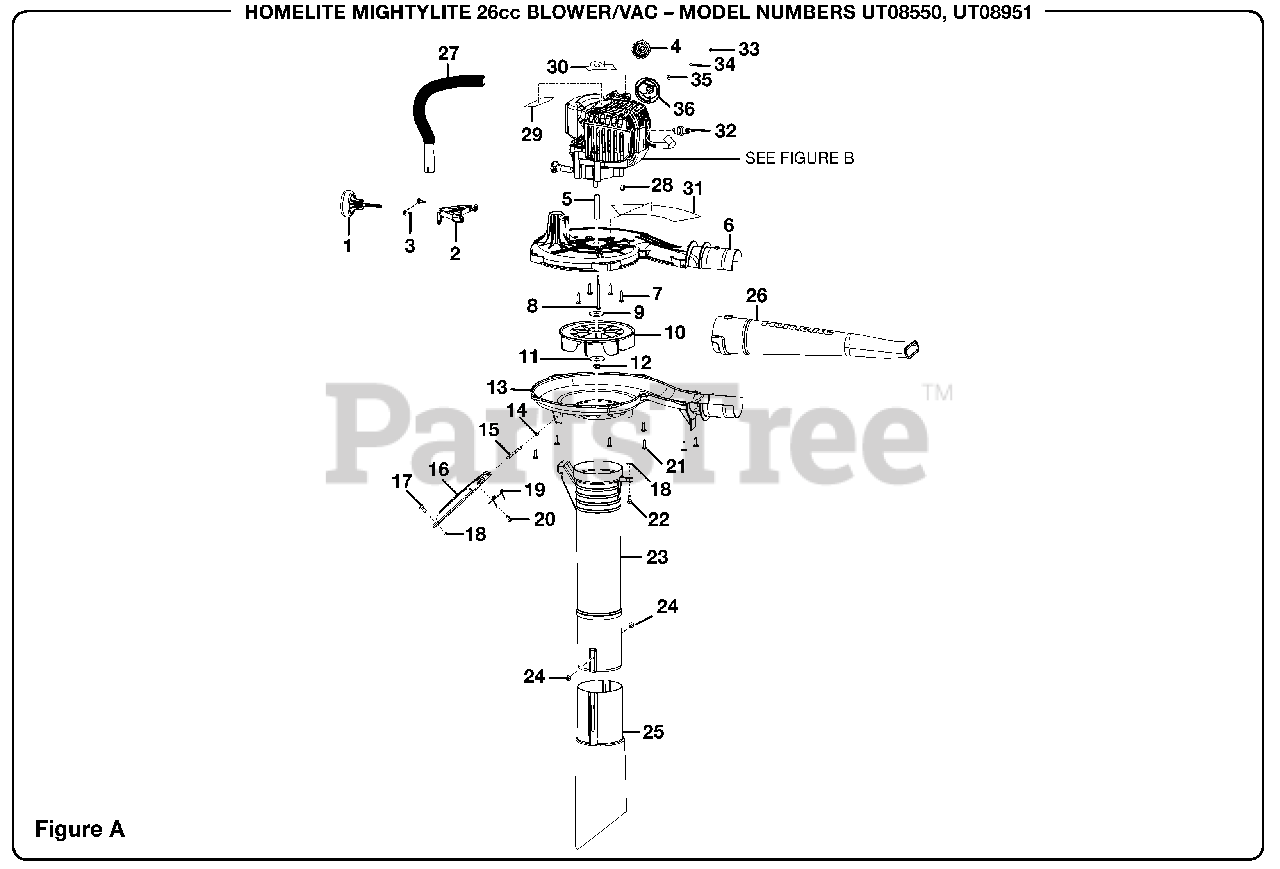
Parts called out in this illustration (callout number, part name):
1	Handle Knob
2	Handle Adaptor
3	Screw (M4, special)
4	Fuel Cap Assembly
5	Spacer (55 mm)
6	Upper Volute
7	Screw (10-14 x 7/8 in.)
8	Screw (M4, special)
11	Flat Washer
12	Hex Nut (3/8-24)
13	Lower Volute
14	E-Ring (4 mm)
16	Vacuum Door
17	Screw (1/4-20, special)
19	Torsion Spring
20	Screw (10-14 x 1/2 in.)
21	Screw (10-14 x 3/4 in., Torx T.F.)
22	Screw (1/4-20, special)
23	Upper Vacuum Tube
24	Screw (10-24 x 1/2 in.,Truss Head Slotted Torx)
25	Lower Vacuum Tube
26	Blower Tube
27	Foam Grip and Handle Assembly
28	Hex Nut (1/4-20)
29	Logo Label
30	Choke Label
31	Starting Label
32	Spark Plug
33	Lock Nut (M4)
34	Wavy Washer (M4)
35	Washer (M4)
36	Choke Dial Cover
